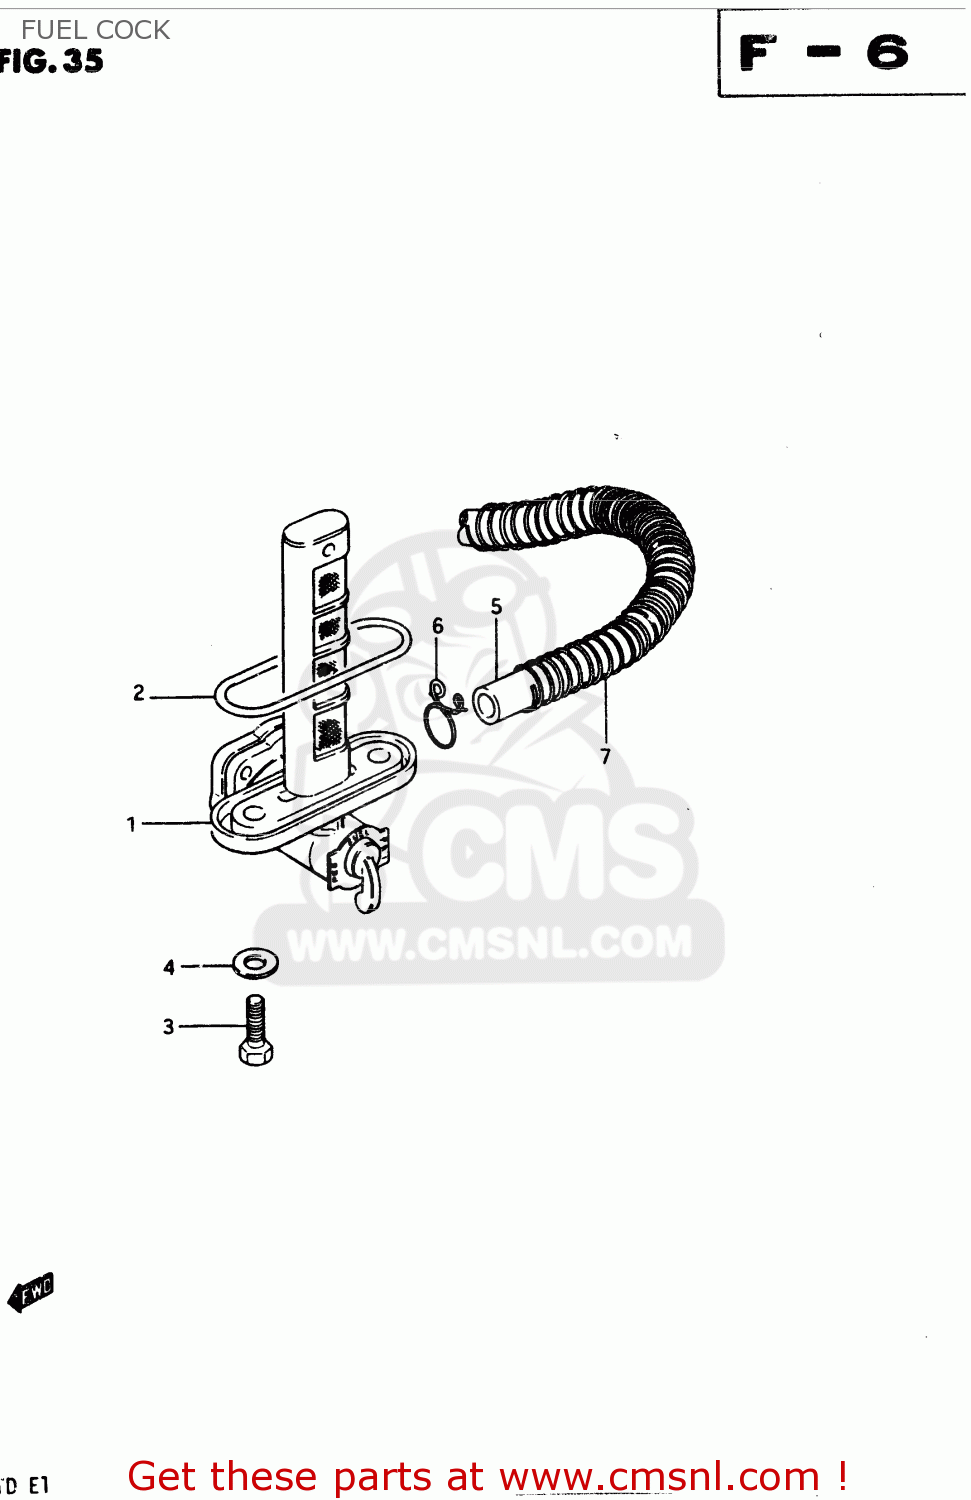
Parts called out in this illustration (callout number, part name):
1	COCK ASSEMBLY,FUEL
2	O RING
3	BOLT(6X20)
4	GASKET
5	HOSE
6	CLIP
7	SPRING
